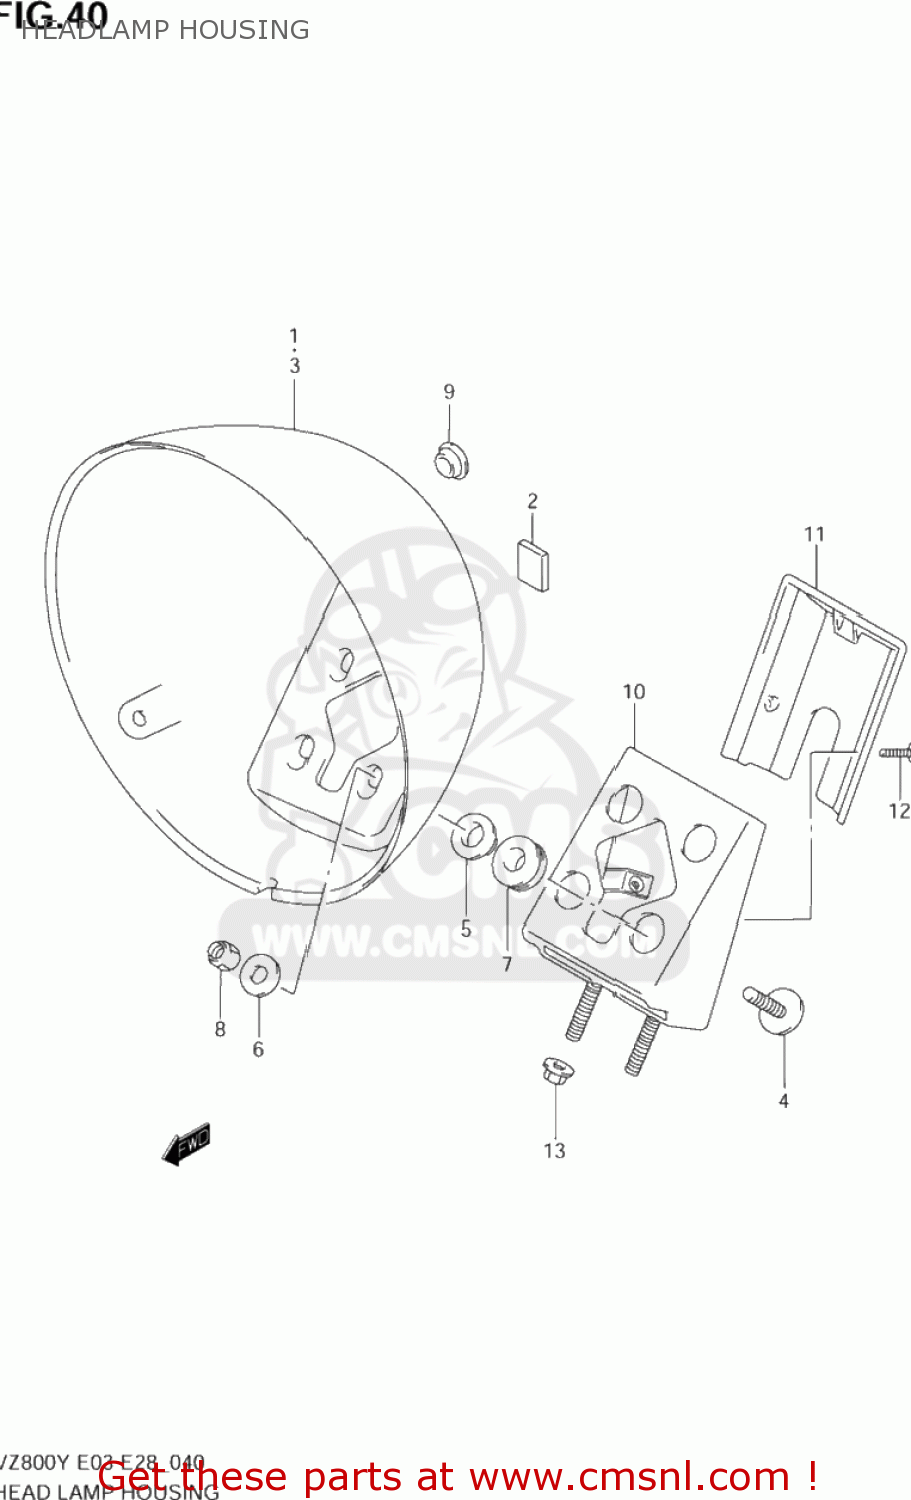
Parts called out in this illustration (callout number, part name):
1	HOUSING,HEADLAMP
2	CUSHION,HEADLAMP HOUSING
3	HOUSING,HEADLAMP
4	BOLT(6X25)
5	WASHER
6	WASHER(6.5X22X2.3)
7	CUSHION
8	NUT
9	CAP,HEADLAMP HOUSING
10	BRACKET,HEADLAMP HOUSING
11	COVER,HEADLAMP HSG BRACKET
12	SCREW
13	NUT
